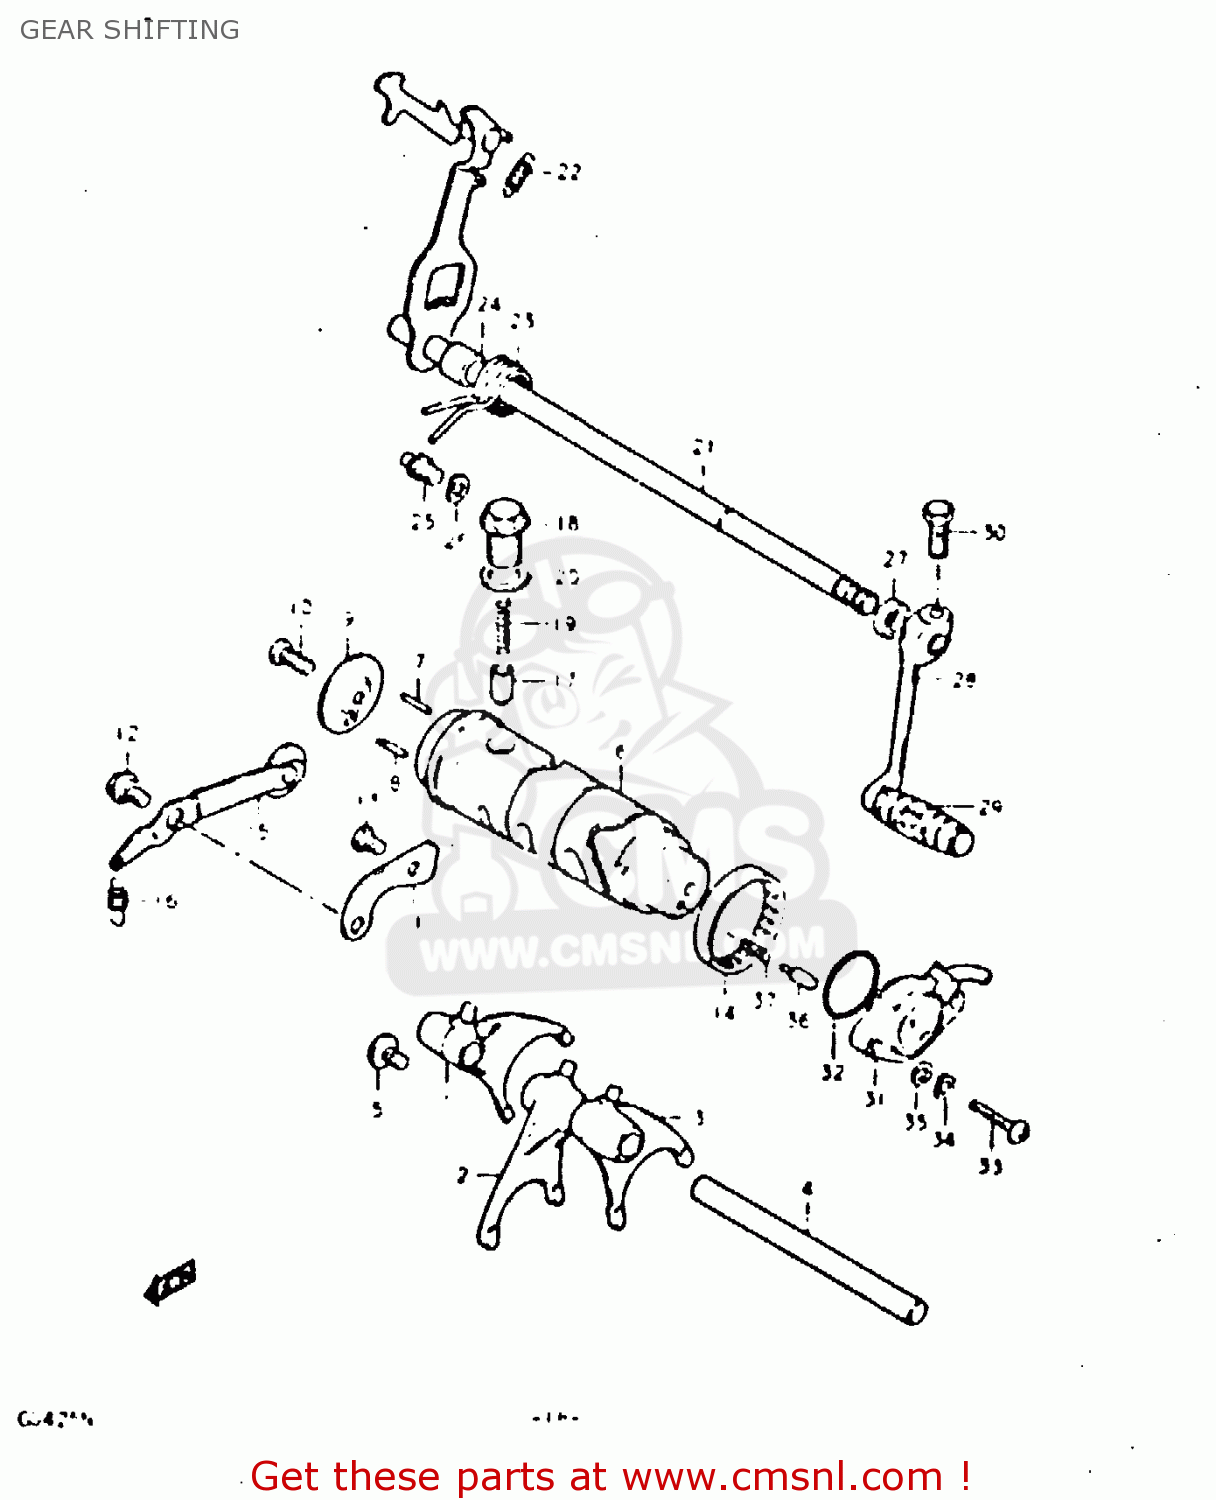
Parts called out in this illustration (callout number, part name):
1	FORK,GEAR SHIFT NO.1
2	FORK,GEAR SHIFT NO.2
3	FORK,GEAR SHIFT NO.2
4	SHAFT,GEAR SHIFT FORK
5	SCREW
6	CAM,GEAR SHIFT
7	PIN(4X18.5)
8	PIN
9	RETAINER,GEAR SHIFT CAM DR PIN
10	SCREW
11	GUIDE,GEAR SHIFTING CABLE
12	BOLT
13	BOLT
14	BEARING(40X47X12)
15	STOPPER,GEAR SHIFT CAM NO.1
16	SPRING
17	STOPPER,GEAR SHIFTING
18	BOLT,GEAR SHAFT CAM STOPPER
19	SPRING
20	GASKET(14X19.2X2) (NAS)
21	SHAFT,GEAR SHIFT
22	SPRING
23	SPRING
24	SPACER(12X20X15.3)
25	STOPPER,GEAR SHIFT CAM
26	WASHER
27	OIL SEAL
28	LEVER ASSY,GEAR SHIFT
29	RUBBER,GEAR SHIFT PEDAL
30	BOLT
31	BASE ASSEMBLY,NEUTRAL SWITCH TERMINAL
32	O-RING (D:2.4 ID:26.2)
33	SCREW 5X20
34	LOCK WASHER
35	WASHER
36	PIN(5X15.5)
37	SPRING
